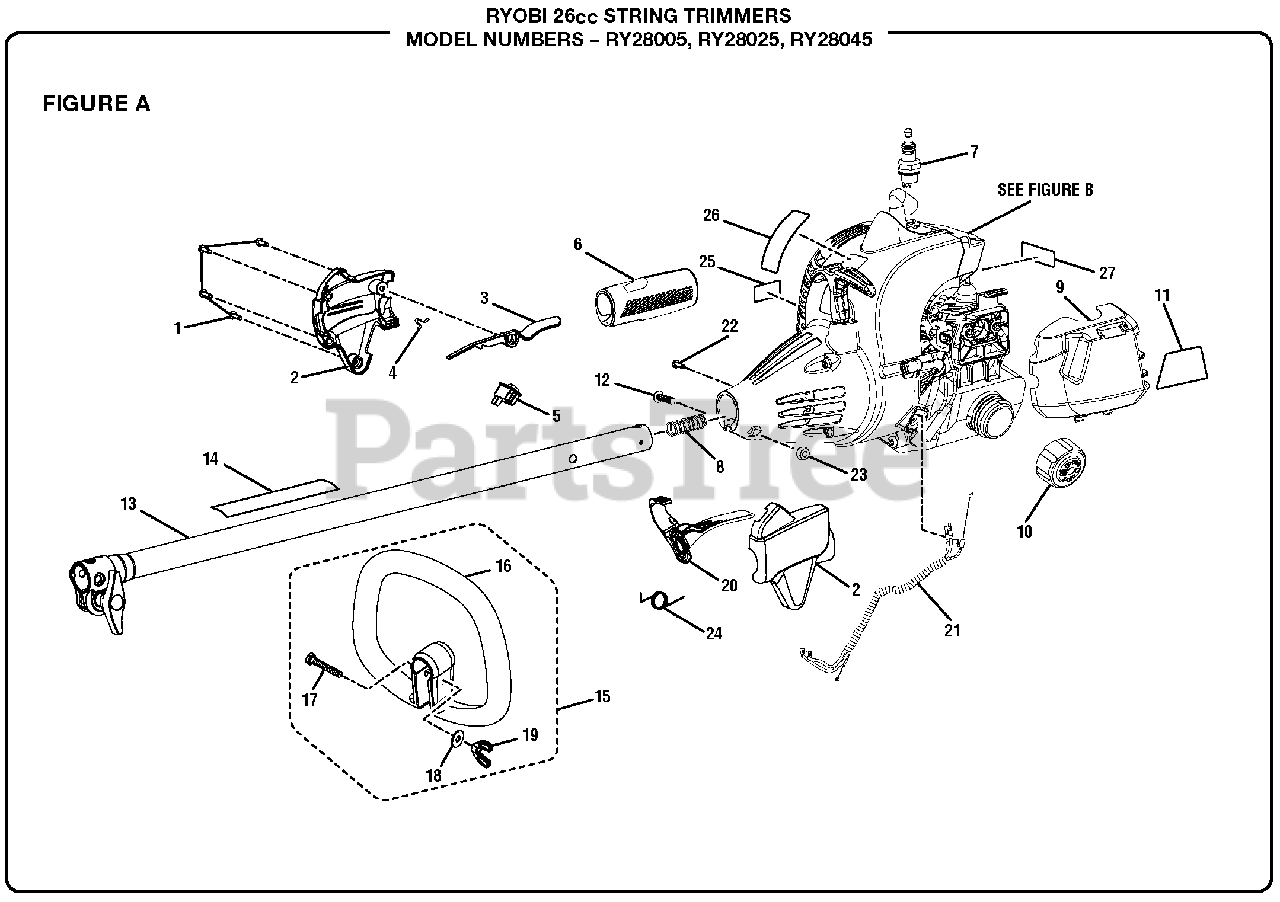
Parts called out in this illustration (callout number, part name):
1	Screw (M4 x 20 mm)
2	Control Handle Assembly
3	Trigger Lock
4	Strap Hanger
5	Switch (Momentary Contact)
6	Rear Handle
7	Spark Plug (Champion RCJ6Y)
8	Compression Spring
9	Air Box Cover
10	Fuel Cap Assembly (1.5 in. Diameter)
12	Bolt (M6 x 20 mm)
13	Upper Boom Assembly
14	Warning Decal
15	Front Handle Assembly
16	Front Handle
17	Bolt (1/4-20 x 40 mm)
19	Wing Nut
20	Throttle Trigger
21	Throttle and Lead Assembly
22	Screw (8-16 x 5/16 in., Torx T.F.)
23	Hex Nut (M6)
25	Combustion Warning Label
26	Logo Label
27	Model Label (EX26)
